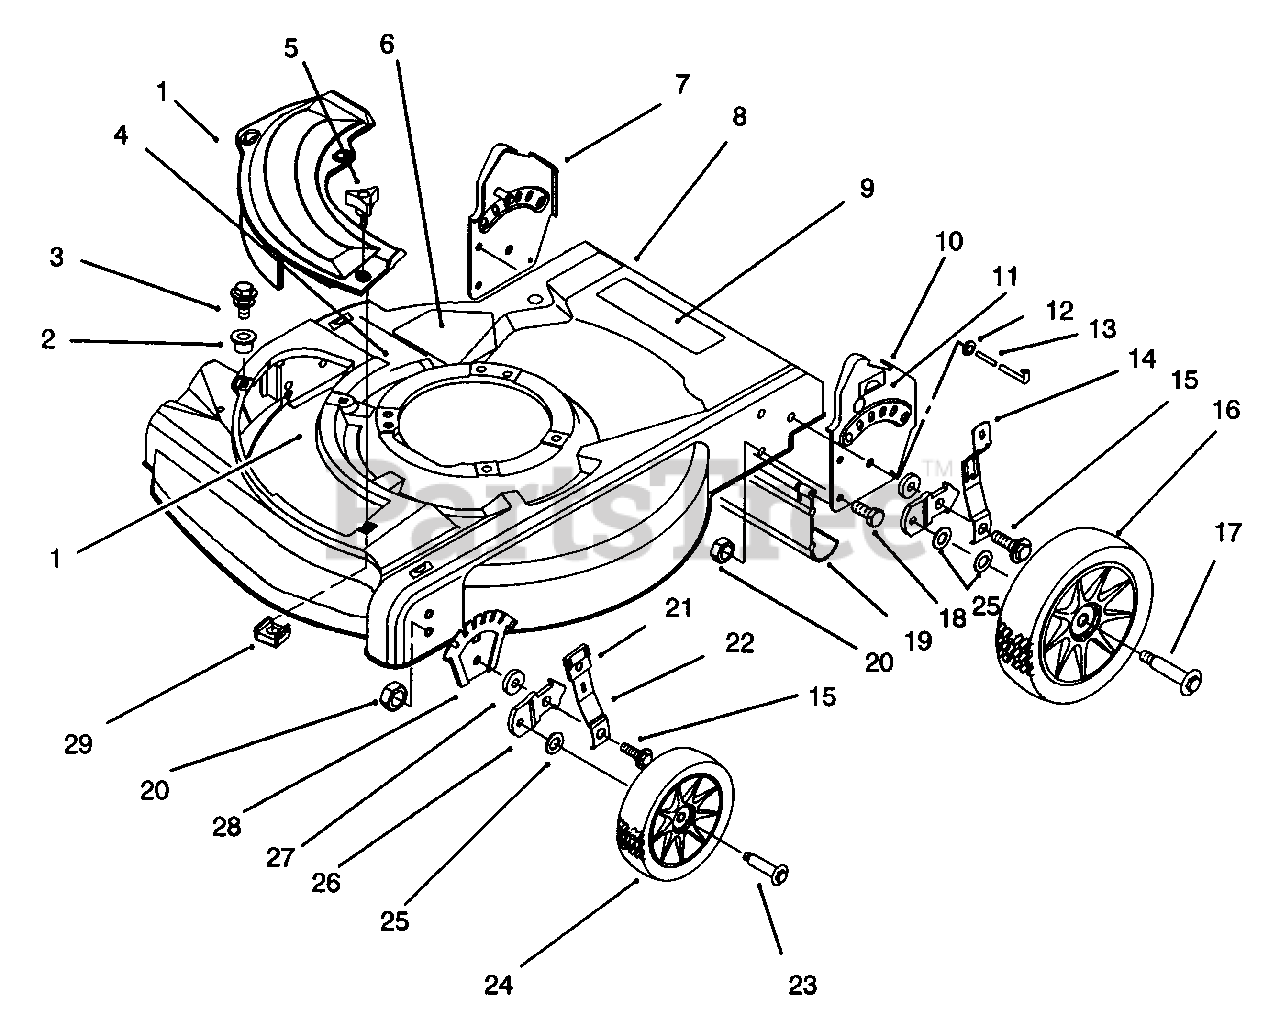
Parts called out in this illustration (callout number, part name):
1	Cover Plate, Mulch
2	Grommet-Plastic
3	Screw-Thread Forming
4	Decal-Danger (English)
5	Knob
6	Decal-Danger (English)
6	Decal-Danger (French/English)
7	Handle Bracket Ass'y-RH
8	Housing & Baffle Ass'y (Incl. Ref. #4, 6, & 11)
9	Decal-Danger (English)
10	Handle Bracket Ass'y-LH
11	Decal-H.O.C. L.H.
13	Rod-Trailing Shield
14	Spring Arm Assembly
15	Bolt-Shoulder
16	Wheel Ass'y-8"
17	Bolt-Wheel
19	Shield-Trailing
21	Knob-H.O.C. Lever
22	Spring Arm Assembly, Front
23	Bolt-Wheel
24	Wheel Ass'y-6"
25	Washer-Wheel Bolt
26	Bracket-H.O.C.
28	Plate-H.O.C. Front
29	Nut-Cage
